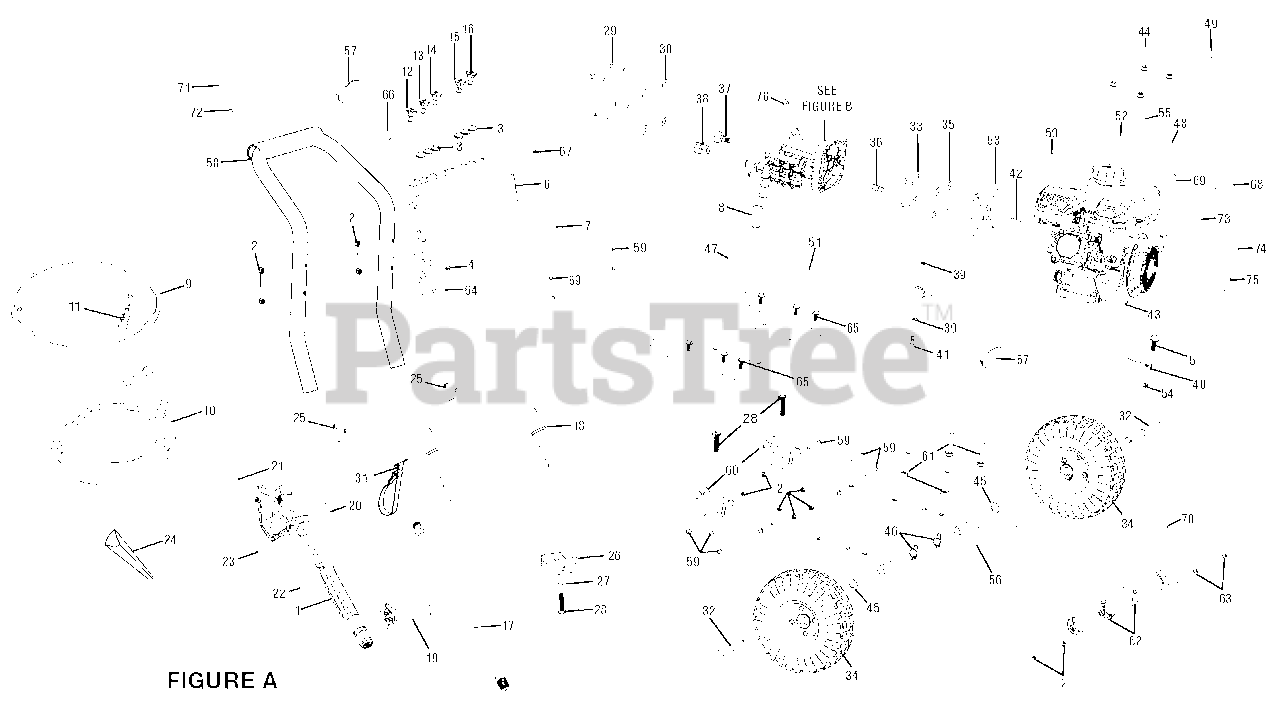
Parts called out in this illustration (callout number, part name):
1	Trigger Handle Assembly
2	Lock Nut (M6)
3	Rubber Grommets
4	Screw (M6 X16 mm, Phillips Pan Hd.)
5	Bolt (M5 x 20 mm)
6	Metal Performance Panel & Nozzle Holder
7	Performance Label
8	Pump Unloader Cap
9	Injection Hose
10	High Pressure Hose (30 ft.)
11	Injection Hose Filter
12	0 Deg Nozzle
13	15 Deg Nozzle
14	25 Deg Nozzle
15	Soap Nozzle
16	40 Deg Nozzle
17	Spray Wand
18	Rear Frame Assembly
19	Auxiliary Handle Assembly
20	Trigger Handle Warning Label
21	Trigger Handle Label
22	Trigger Handle Max Pressure Label
23	Trigger Handle Warning Label
25	Lock Button w/Spring Clip
27	Washer (1/4 in.)
28	Screw (M6 x 25 mm,T30 Torx Hd.)
29	Bolt (3/8-16 x 1-3/8 in., Hex Hd.)
30	Washer (3/8 in.)
31	Hose Storage Strap
33	Bolt (5/16-24 x 3/4 in., Hex Hd.)
35	Washer (5/16 in.)
36	Thermal Release Valve
37	Garden Hose Coupler w/Filter
38	Quick Disconnect (Female)
39	Seal
40	Idle Down Assembly
41	Idle Down Bolt (M10 x 1.5 mm, Banjo)
42	Output Shaft Key (35 mm)
43	"Ridgid 212cc" Horizontal Engine
44	Lock Nut (M8 x 1.25)
45	Washer (1/2 in.)
46	Hitch Pin
47	Combustion Warning Label
48	Danger Label
49	Notice Hang Tag
50	E-85 Label
51	Check Oil Label
52	Hot Muffler Label
53	Pump Flange
54	Cable Clamp
55	Pressure Release Label
56	Main Frame Assembly
58	Handle Assembly
59	Bolt (M6 X 48 mm, T30 Torx Hd.)
60	Connector
61	Bolt (M8 x 1.25 x 40 mm, Flange Hd.)
62	Lower Frame Cover
63	Screw (M6 x 55 mm, T30 Torx Hd.)
64	Wand Holder
65	Bolt (M6 x 16 mm, Flange Hd.)
66	Nozzle Hang Tag
67	Extra Nozzle Label
68	Idle Down Label
69	Oil Dipstick Hang Tag
70	Logo Label
71	Quick Start Label
72	Inquires Label
73	On/Off Label
74	Choke & Fuel Label
75	Recoil Housing Label
76	Vent Cap Hang Tag
